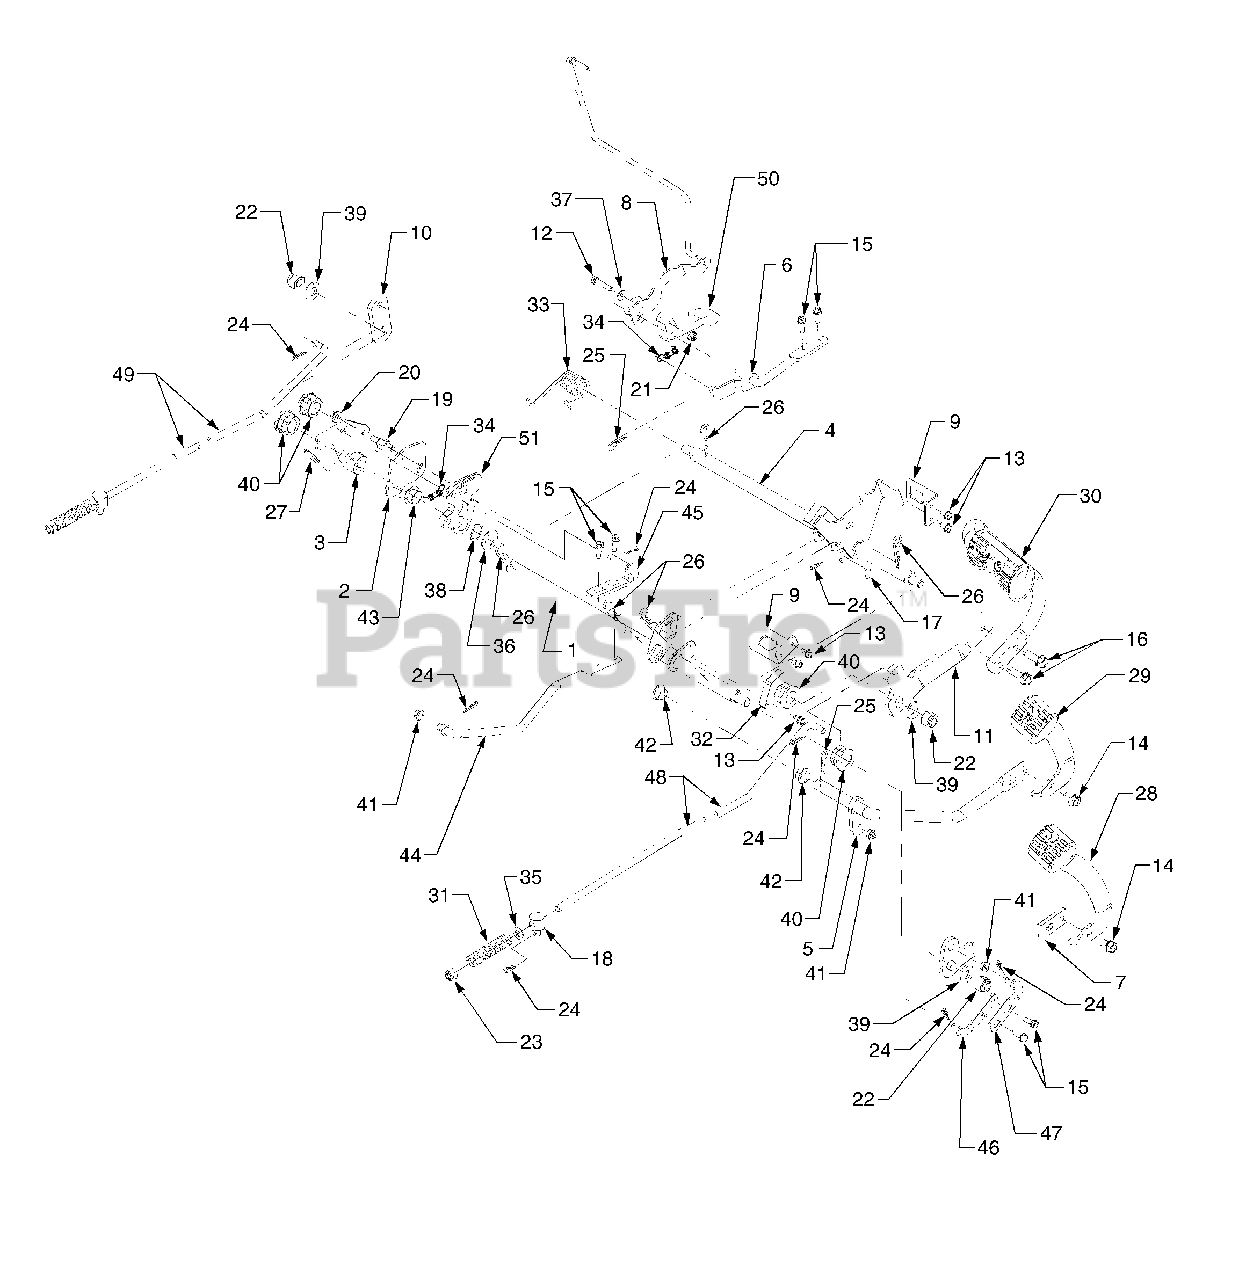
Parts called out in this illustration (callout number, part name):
1	Shaft Assembly, Pedal
2	Plate, Disengagement
4	Shaft Assembly, Brake
5	Shaft Assembly, Reverse
6	Rod Assembly, Cruise
7	Link, Pedal Mounting
8	Bracket, Rod Adjust
9	Bracket, Switch
10	Lever, Brake
11	Link, Brake Pedal
12	Screw, Hex Cap, 1/4-20 x 1.25 GR5
13	Screw, Hex Wash. Hd. Tapp 1/4-20 x .5
14	Screw, Hex Wash. Hd. Tapp 3/8-16 x .75
15	Screw, Hex Wash. Hd. Tapp 1/4-20 x .75
16	Screw, Hex Wash. Hd. Tapp 3/8-16 x 1.25
17	Pin, Clevis, 3/8 x 2.015
18	Ferrule, Adjust.
19	Stud, Actuator
20	Nut, Hex Flange Lock, 5/16-18
21	Nut, Hex Flange Lock, 1/4-20
22	Nut, Hex Insert Lock, 1/2-20
23	Nut, Hex Lock, 3/8-24
24	Pin, Internal Cotter
25	Pin, Internal Cotter
26	Pin, Internal Cotter
27	Pin, Spiral Spring, .25 x 1.5
28	Pedal, Forward
29	Pedal, Reverse
30	Pedal, Brake
31	Spring, Compression
32	Spring, No Cut Reverse
33	Spring, Torsion
34	Spring, Extension, .380 OD x 1.44
35	Washer, Flat, .406 x .75 x .063
36	Washer, Flat, .79 x 1.24 x .060
37	Washer, Flat, .25 x .62
38	Washer, Wave, .785 x 1.0 x .012
39	Washer, Flat, .531 x 1.06 x .134
40	Bearing, Hex Flange
41	Bearing, Flange
42	Bearing, Flange
43	Bearing, Flange
44	Rod, Rear Control
45	Rod, Front Control
46	Rod, Rear Connecting
47	Rod, Front Connecting
48	Rod, Brake RH
49	Rod, Brake LH
50	Cruise Latch
51	Plate, Cruise
